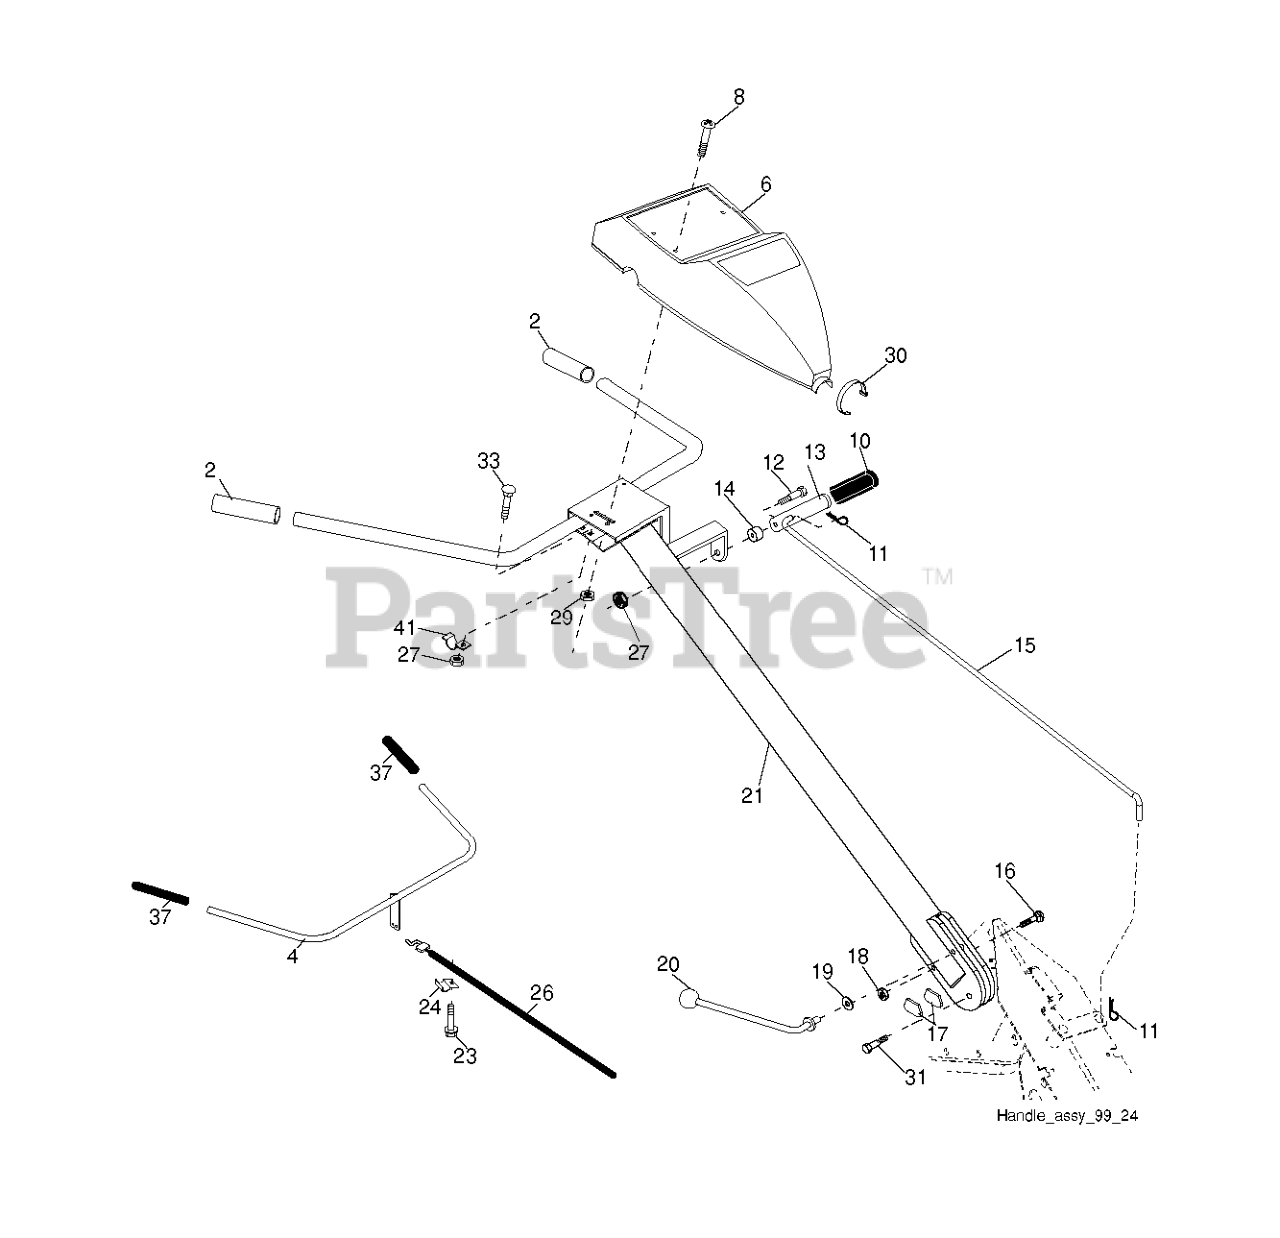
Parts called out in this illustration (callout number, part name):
2	GRIP.1X5.06
4	CONTROL BAR ASSY
6	RP PANEL, CONTROL
8	SCREW.PNHD.10-24
10	GRIP T
11	RETAINER M
12	SHOULDER BOLT ST
13	HANDLE.SHIFT.TILLER
14	GROMMET.RUBBER.CRT.TILLER
15	SHIFT ROD CRT
16	BOLT D
17	LOCK.HANDLE.CRT
19	WASHER CRT
20	LEVER.LOCK.CRT
21	HANDLE.ASM.TILLER.GREY.
23	TAPPING SCREW
24	CONDUIT.CLIP.PLATED
26	CABLE.CLUTCH
27	NUT T
29	NUT **
30	TIE CABLE CRT
31	BOLT.PIVOT
33	BOLT
37	GRIP BAR CRT(1)
41	CLAMP.BAR.CRT.BLACK
